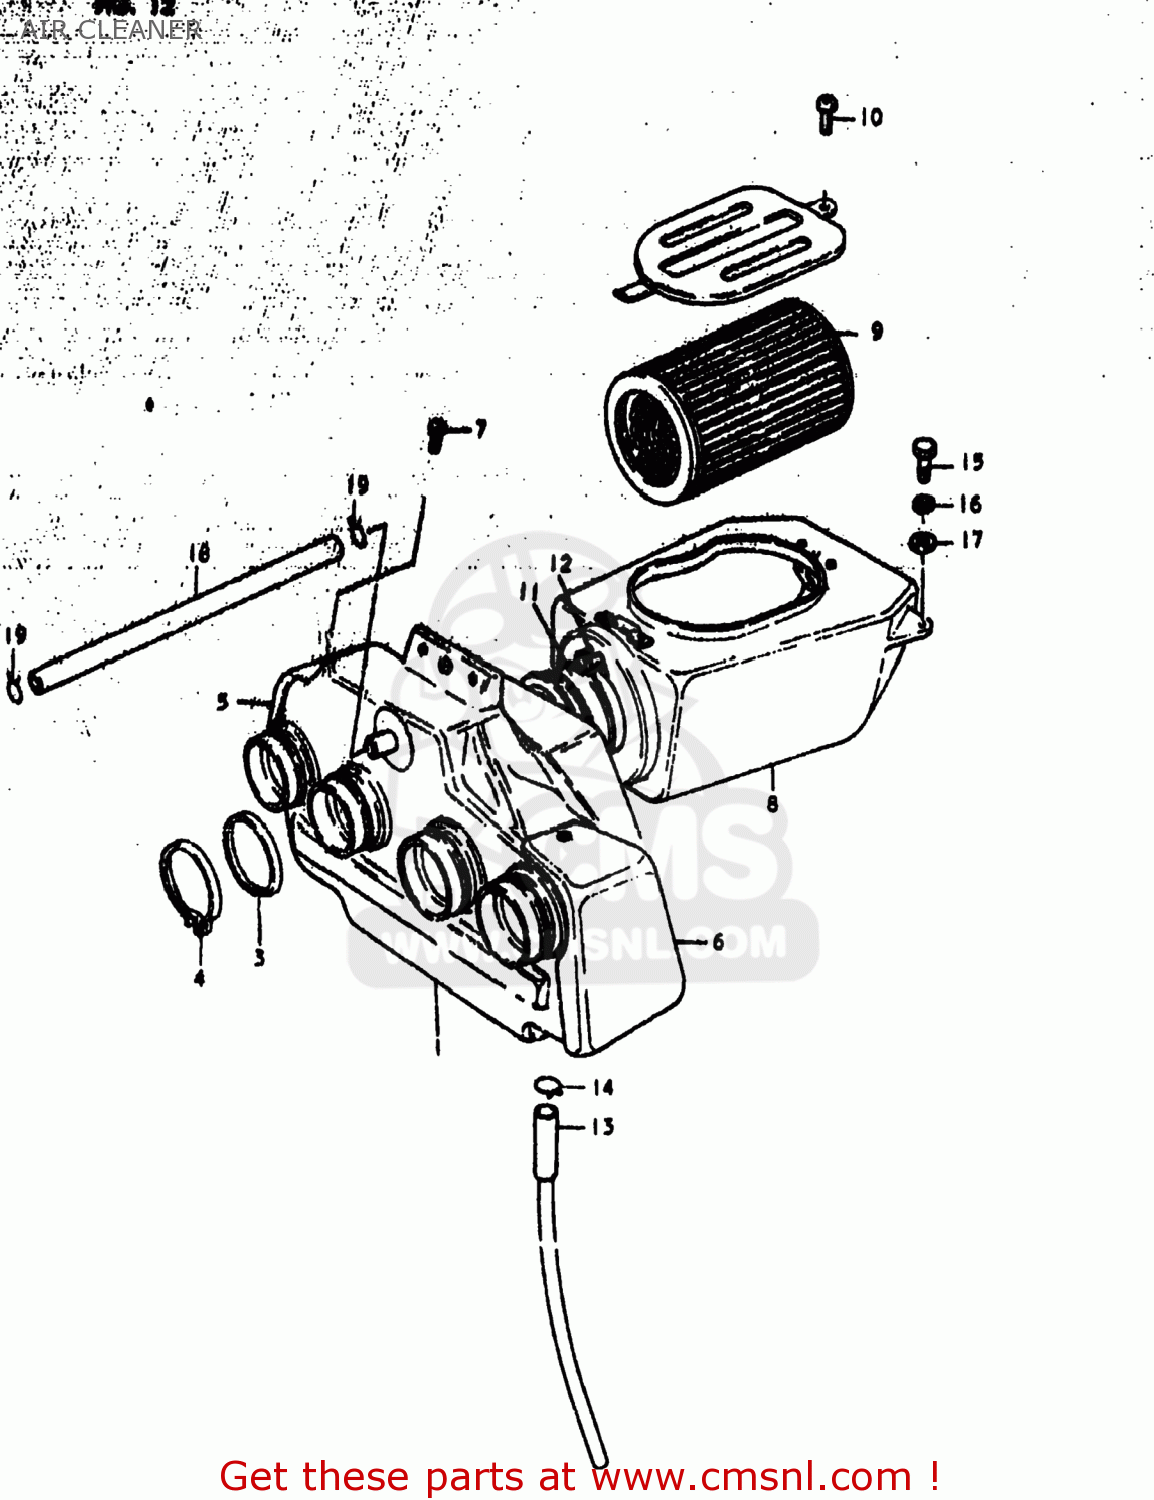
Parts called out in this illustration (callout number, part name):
1	CASE,AIR CLEANER,FRONT
2	TUBE,AIR CLEANER OUTLET
3	RING,CARBURETOR AIR IN
4	CLAMP
5	COVER,CASE,RIGHT
6	COVER,CASE,LEFT
7	SCREW
8	CASE ASSEMBLY,AIR CLEANER
9	FILTER,AIR CLEANER
10	SCREW
11	HOSE,AIR CLEANER
12	BAND
13	DRAIN TUBE
14	CLIP
15	BOLT, UPPER
16	LOCK WASHER
17	WASHER
18	HOSE
19	CLIP
